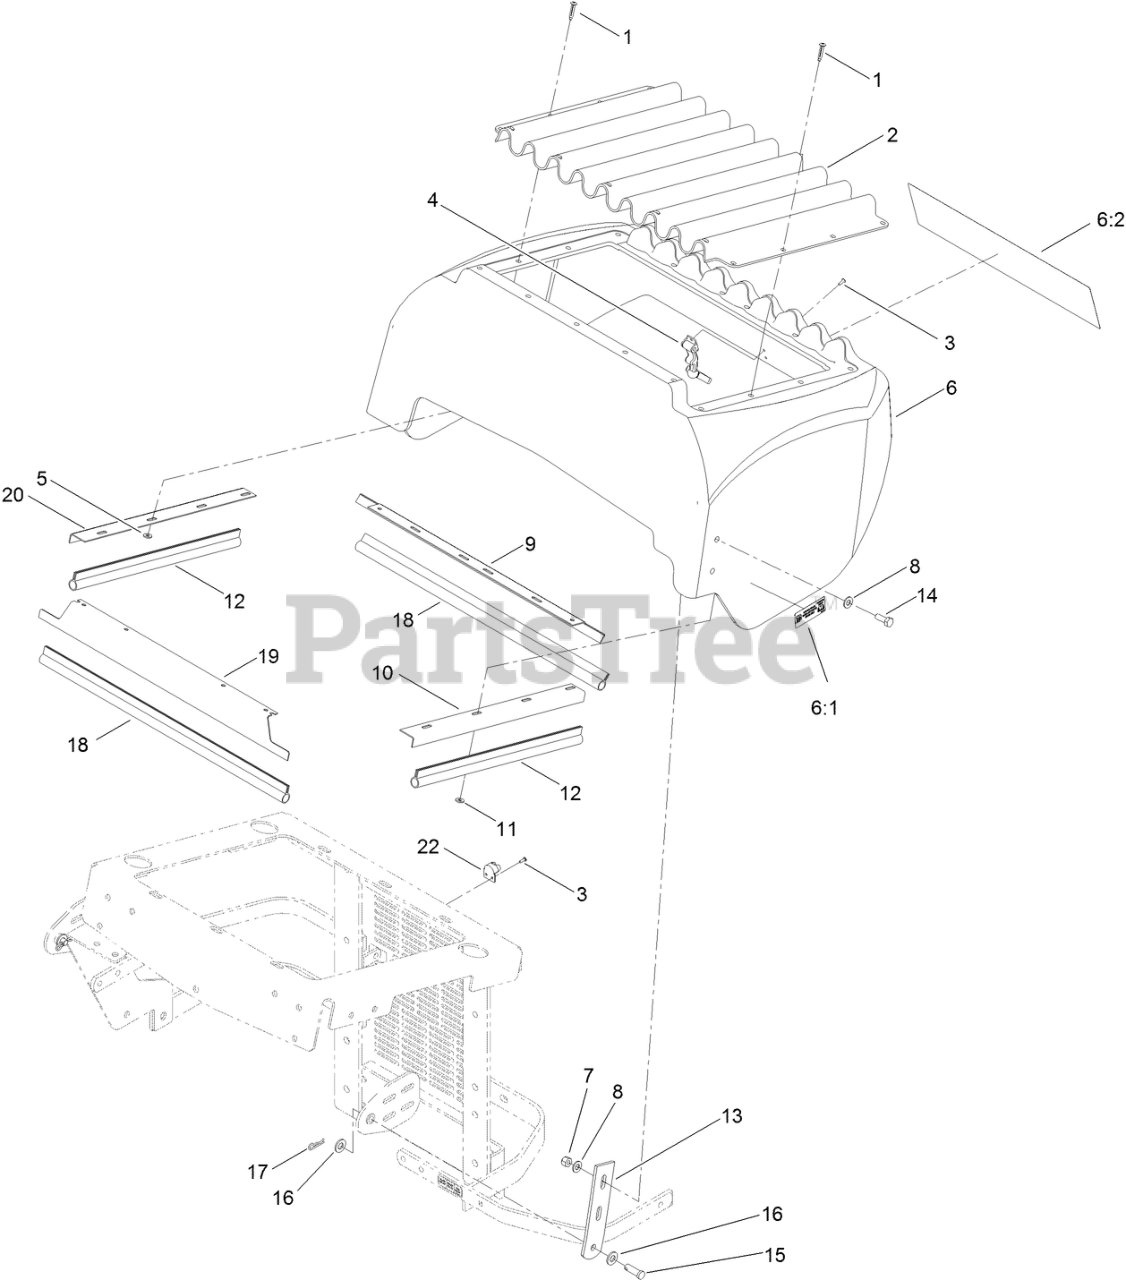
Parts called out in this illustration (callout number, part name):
2	SCREEN-RADIATOR
3	RIVET
4	LATCH-RUBBER
5	WASHER-SPRING
6	HOOD ASM
6:1	DECAL-LOW SULFUR
7	NUT-LOCK, NI
8	WASHER-PLAIN
9	ANGLE-RADIATOR, BOTTOM
10	ANGLE-RADIATOR, LH
11	WASHER-FLAT
12	SEAL-TRIM
13	PLATE-HINGE, HOOD
14	SCREW-HH
15	PIN-CLEVIS
16	WASHER-FLAT
17	PIN-COTTER
18	SEAL-TRIM
19	ANGLE-RADIATOR, TOP
20	ANGLE-RADIATOR, RH
22	KEEPER
